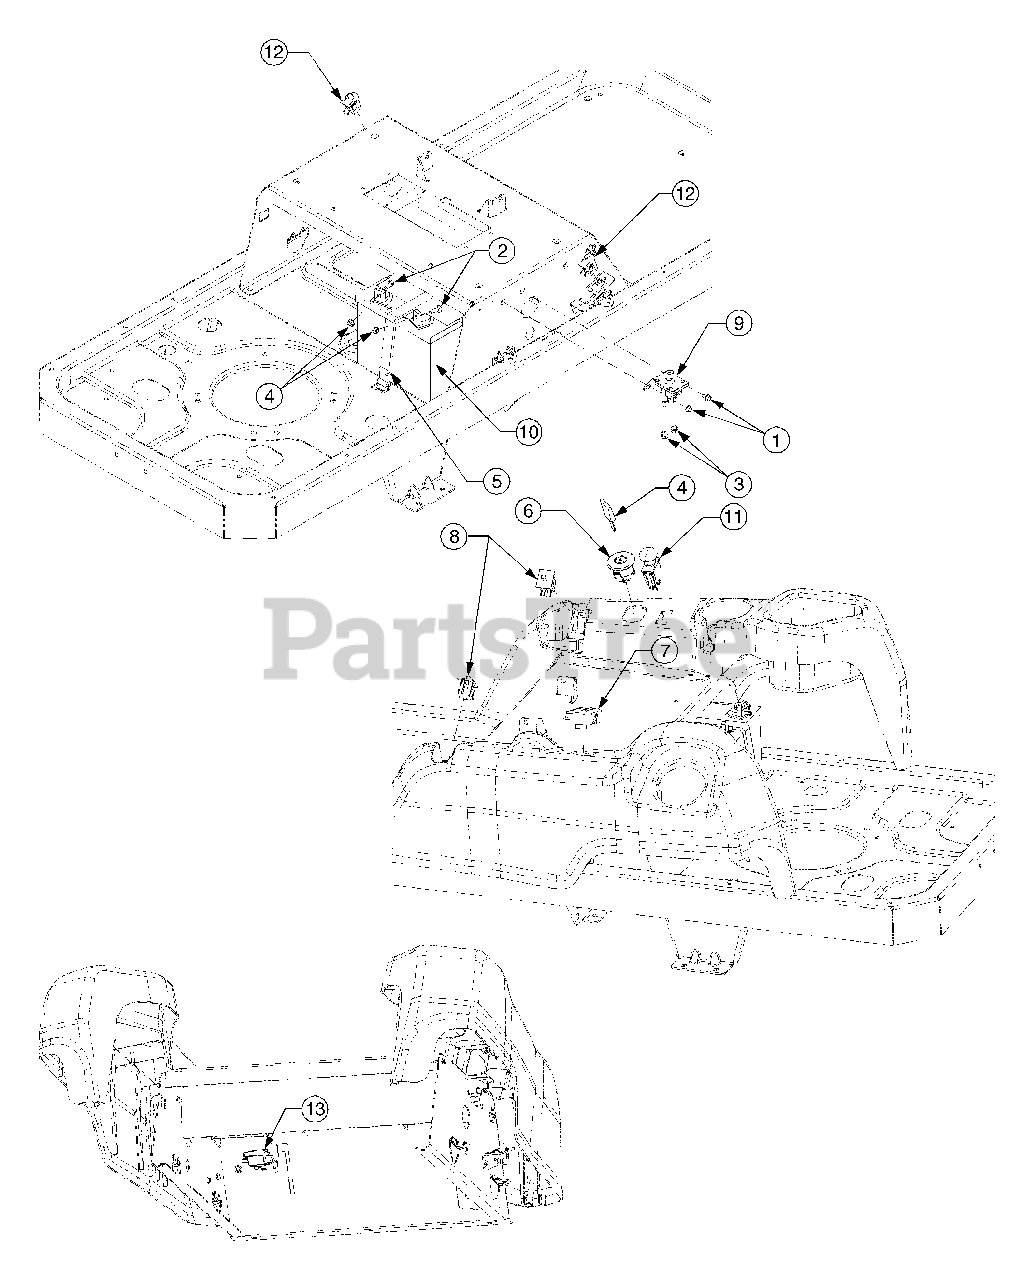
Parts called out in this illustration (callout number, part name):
1	Screw, Hex Wash. Hd. Tapp, 1/4-20 x .5
2	Screw, Hex Cap, 1/4-20 x .75 GR5
3	Nut, Hex Sems, 1/4-20
4	Key
5	Strap, Battery
6	Switch, Ignition
7	Meter, Hour
8	Switch, Dbl. Pole - Neutral
9	Solenoid
10	Battery, 245 CCA
11	Switch, PTO
12	Switch, Snap Mount (N.C.) - Reverse
13	Switch, 3-Pole, (NC-NO-NO) - Brake
